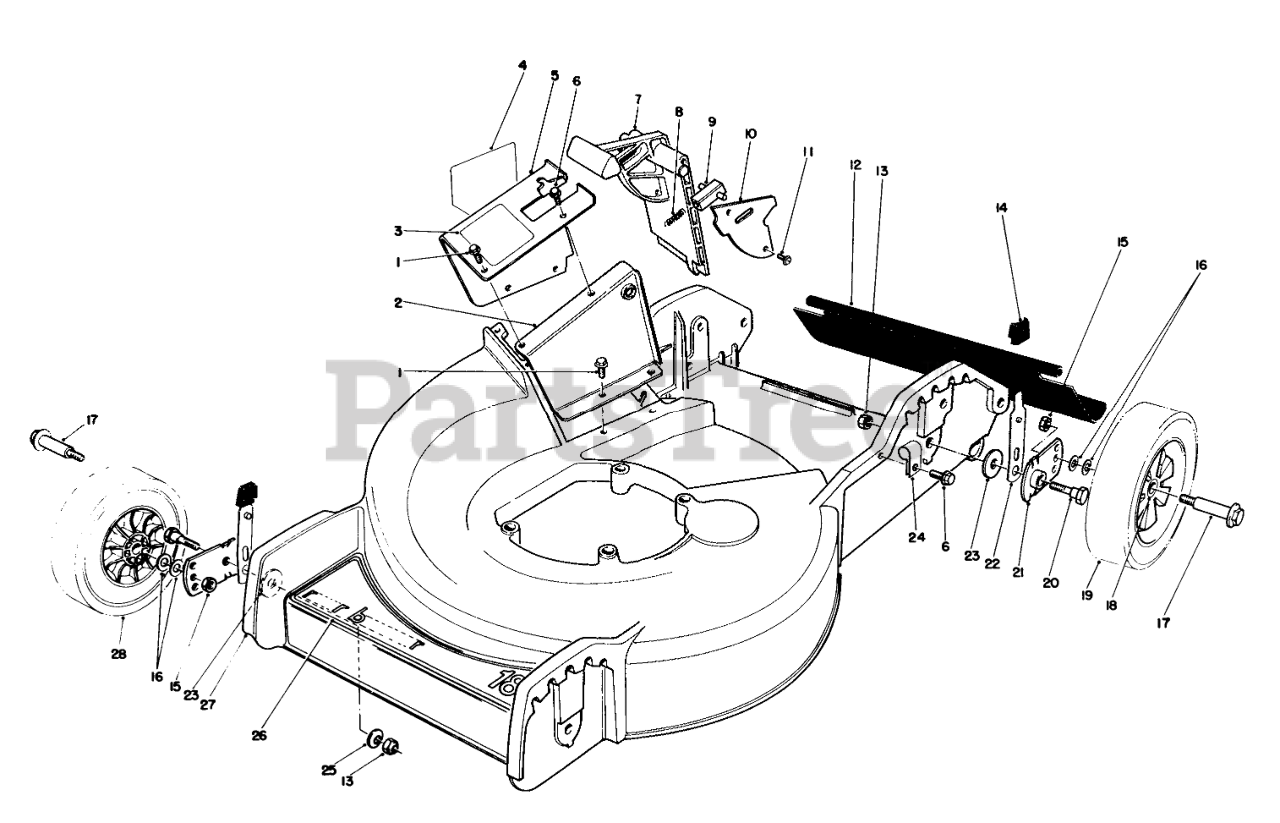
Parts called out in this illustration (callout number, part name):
1	SCREW
2	Tunnel-Inner
3	CAUTION DECAL
4	Decal-Danger
5	Tunnel-Outer (Incl. Ref. #3 & 4)
6	SCREW
7	Door Mulching
8	SPRING-COMPRESSION, LATCH
9	Door Latch
10	Cover Door
12	SHIELD - TRAILING
13	NUT-LOCK, NI
14	KNOB-ARM
15	Nut
16	WASHER
17	BOLT-WHEEL
18	BUSHING
19	Wheel & Tire Assembly (Incl. Ref. #18)
20	PIVOT SCREW
21	PIVOT ARM ASSY
22	SPRING ARM ASM
23	PIVOT WASHER
24	CLAMP-R
25	WASHER-BELLEVILLE
26	DECAL-DECK
27	HSG & CARTON
28	Wheel & Tire Assy. (Incl. Ref. #18)
